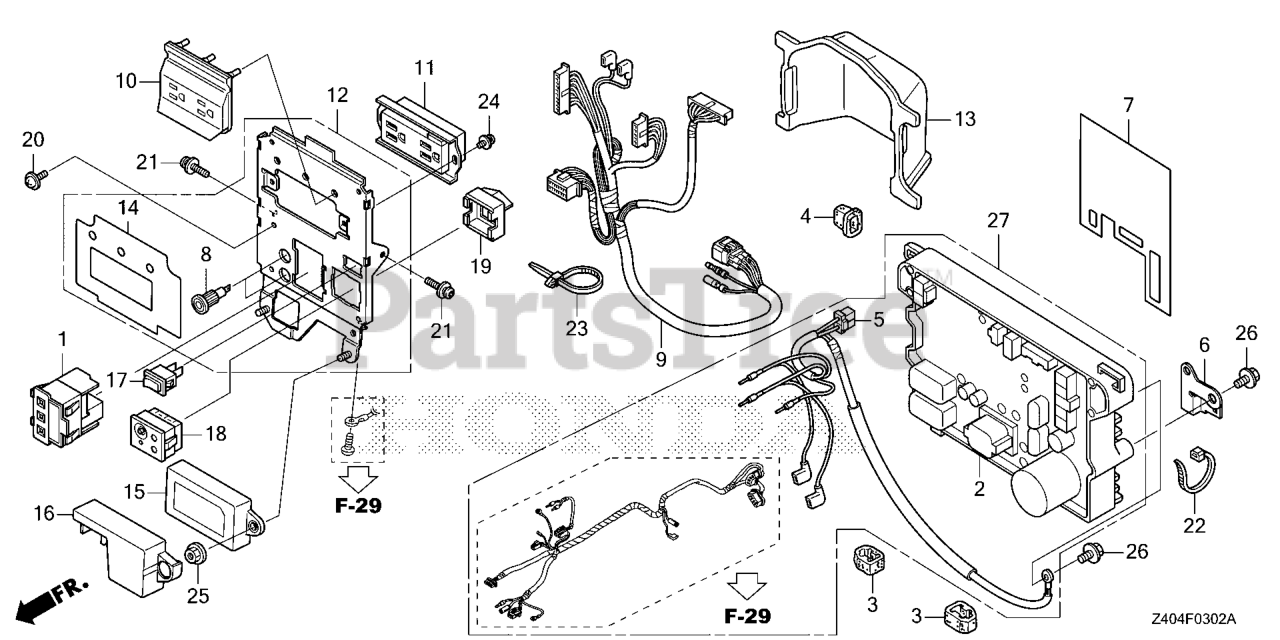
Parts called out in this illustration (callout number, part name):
1	SPARK UNIT
2	UNIT COMP, INVERTER
3	RUBBER A, INVERTER
4	RUBBER B, INVERTER
5	SUB-WIRE HARNESS ASSY.
6	BRACKET, CONNECTOR
7	SHEET, WATERPROOF
8	SOCKET, COMPOSITE
9	WIRE HARNESS ASSY., CONTROL
10	COVER, RECEPTACLE (15A-125V)
11	RECEPTACLE ASSY. (125V-15A)
12	PANEL, CONTROL
13	COVER, CONTROL PANEL
14	MARK, CONTROL PANEL
15	SENSING UNIT (CO)
16	COVER, SENSING UNIT PROOF (CO)
17	SWITCH, AUTO-THROTTLE (OTAX)
18	LED ASSY., INDICATER
19	COVER, LED INDICATOR PROOF
20	SCREW, PAN (5X12) (GROUND CABLE)
21	BOLT-WASHER (5X20) (TORX)
22	BAND, WIRE (165MM) (BLACK)
23	TIE, CABLE
24	SCREW-WASHER (4X6)
25	NUT, FLANGE (5MM)
26	BOLT, FLANGE (6X10)
